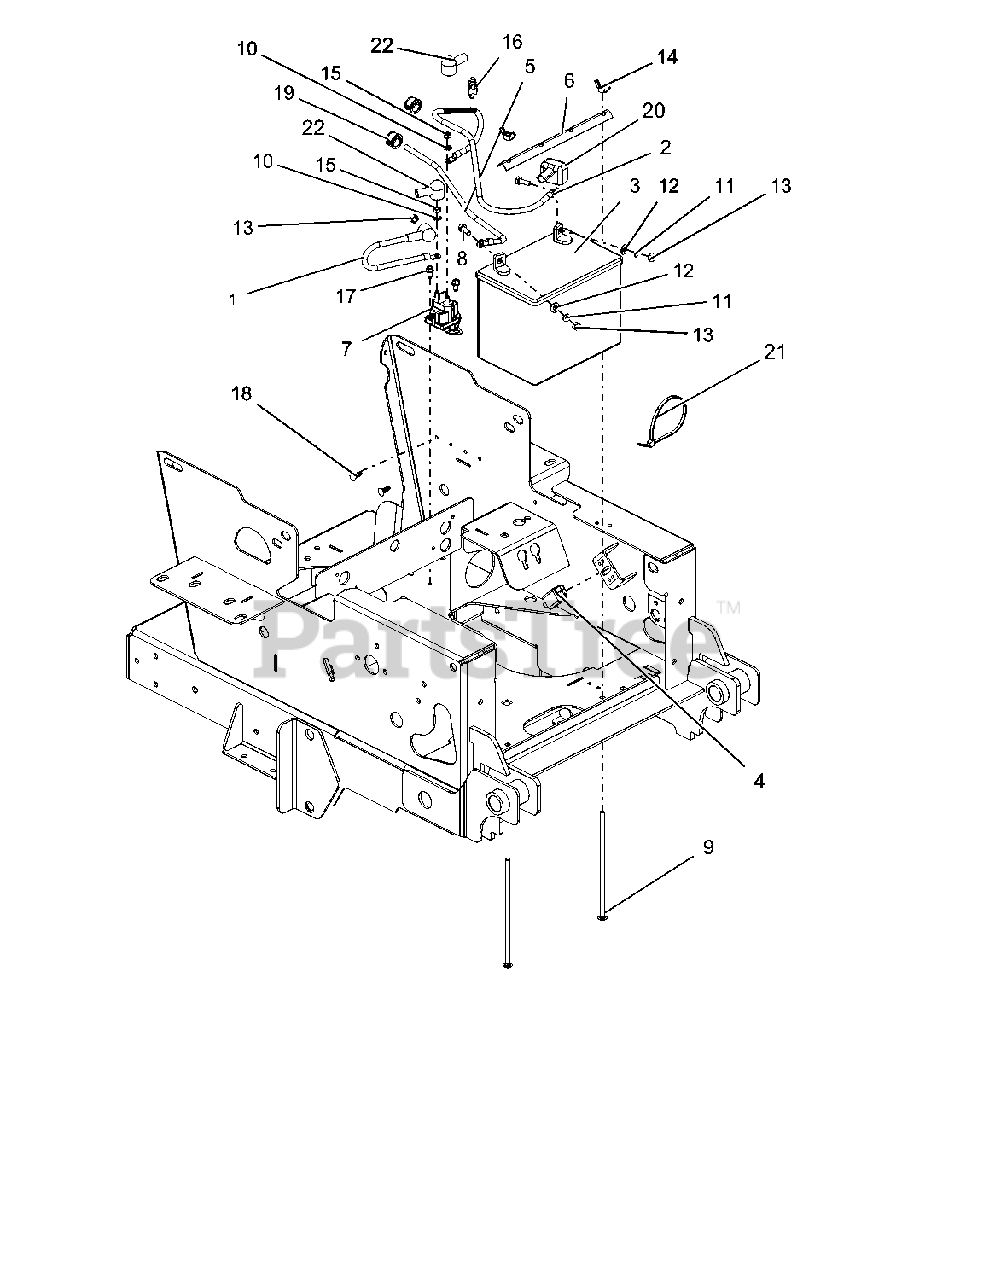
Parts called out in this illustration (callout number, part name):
1	CABLE, POS W/(2) 1/4 RING 9.0 LG
2	CABLE, POS W/(2) 1/4 RING 9.0 LG
3	BATTERY, 300 CCA 10U1L
4	SWITCH, SINGLE POLE N.O.
5	CABLE, NEGATIVE BATTERY 24"
6	HOLD DOWN - BLK
7	SOLENOID, STARTER (SEALED)
8	BLT-HEX .25-20X.75 GR5 YWZC
9	BLT-RDHDSQNK .25-20X7.50 G2 YWZC
10	@, WSHR-LK-EXT.262X.502X.026 YWZC
11	WSHR-LK .25X.062 REG YWZC
12	WSHR-FL-STL.281X.62X.065 YWZC
13	NUT-HEX .25-20 YWZC
14	NUT-LOCKING WING 1/4-20
15	NUT-HEX M6-1.00 YWZC
16	CLIP, T, .31-.38
17	SCR-TAP .25-20X.50 HWH TR YWZ
18	RIVET, .25 NYLON PANEL
19	BUSH, PANEL SNAP .687X.875X.56
20	INSULATOR
21	CABLE, TIE 5.50 LG
22	BOOT, EYELET TERMINAL
